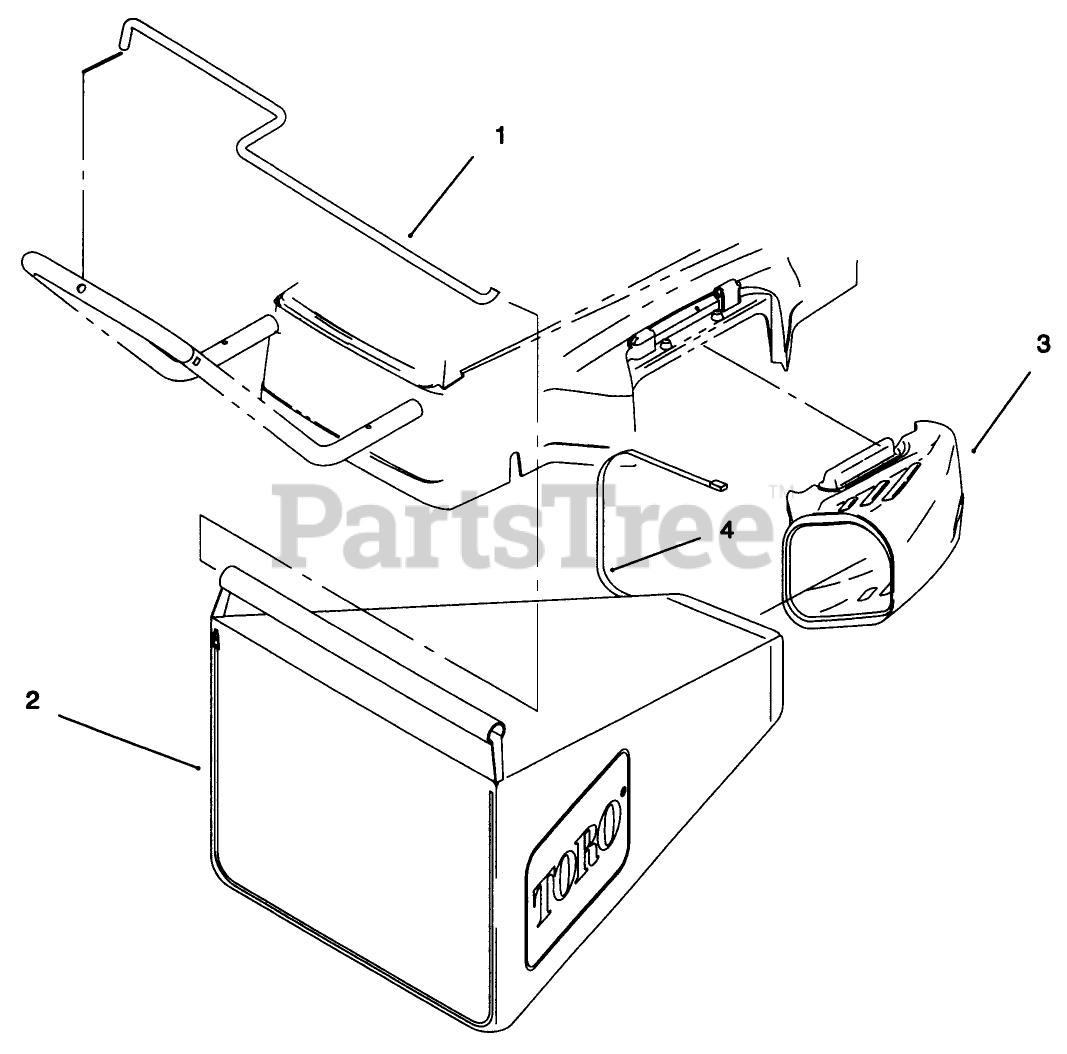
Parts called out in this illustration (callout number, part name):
2	ASSEMBLY - BAG TORO
3	CHUTE - BAG
4	TIE-CABLE
